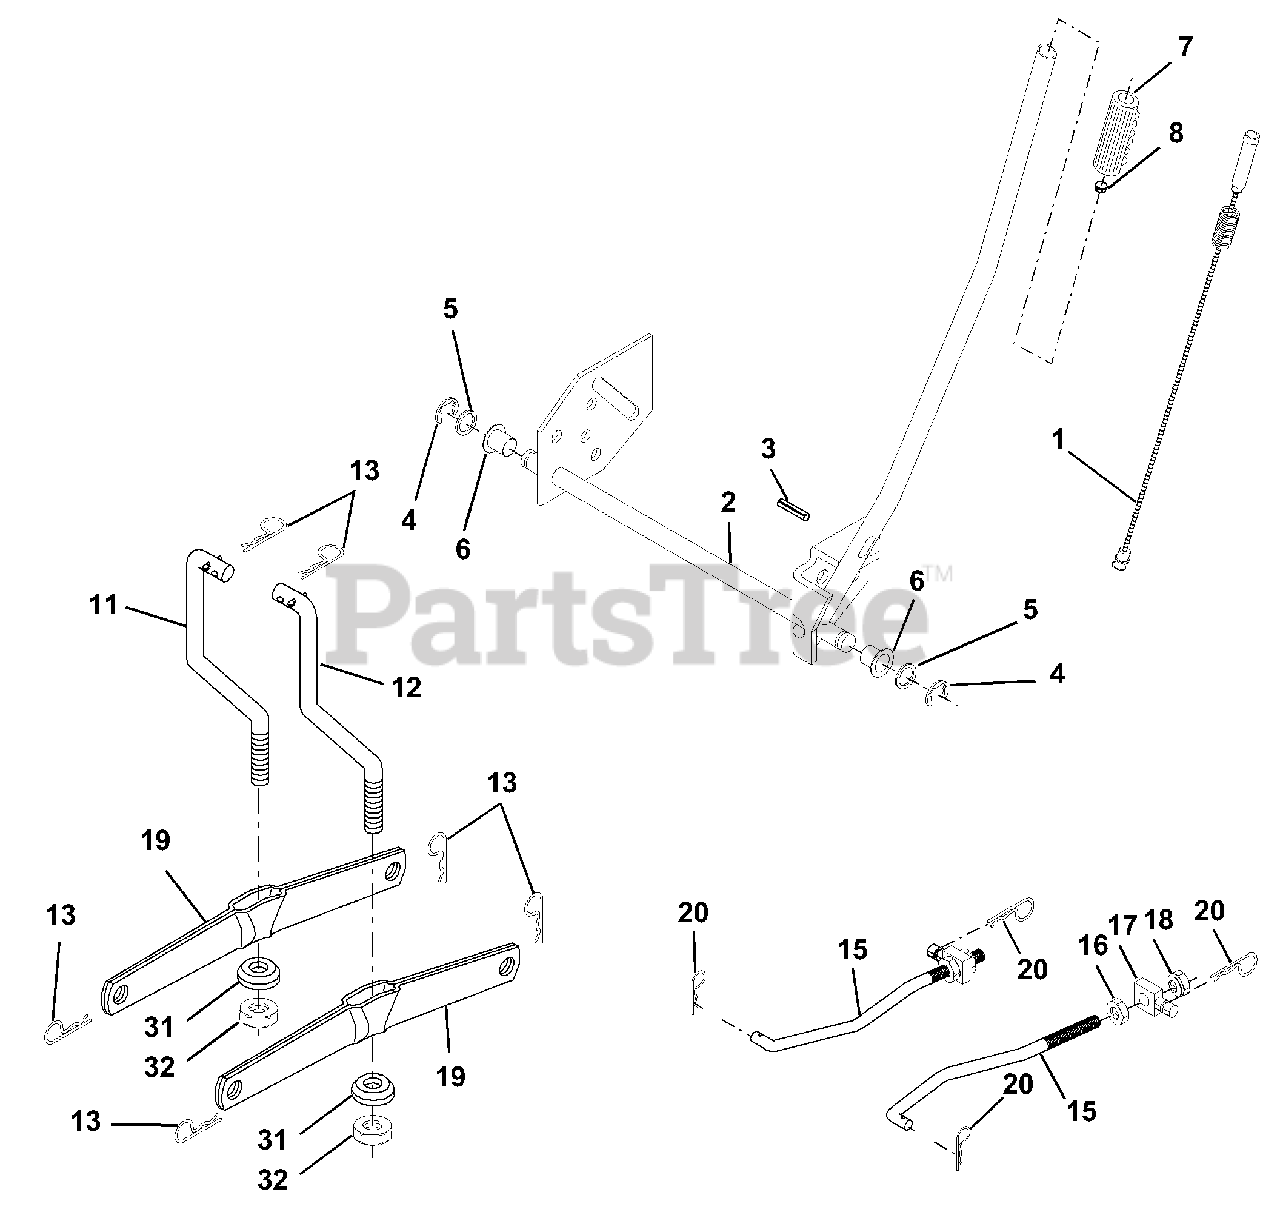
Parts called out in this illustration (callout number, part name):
1	Wire Asm Inner/Sprg w/Plunger
2	Shaft Asm Lift
3	Pin Groove
4	E Ring #5133-62
5	Washer 21/32 x 1 x 21 Ga.
6	Bearing Nylon
7	Grip Handle
8	Button Plunger
11	Link Lift Lh
12	Link Lift Rh
13	Retainer Spring
15	Link Front
16	Nut Jam Hex 1/2-13 Unc
17	Trunnion Blk Zinc
18	Nut Lock W/Wsh 1/2-13 Unc
19	Arm Suspension Rear
20	Retainer Spring
31	Bearing Pvt Lift Spherical
32	Nut Crownlock 3/8-24
